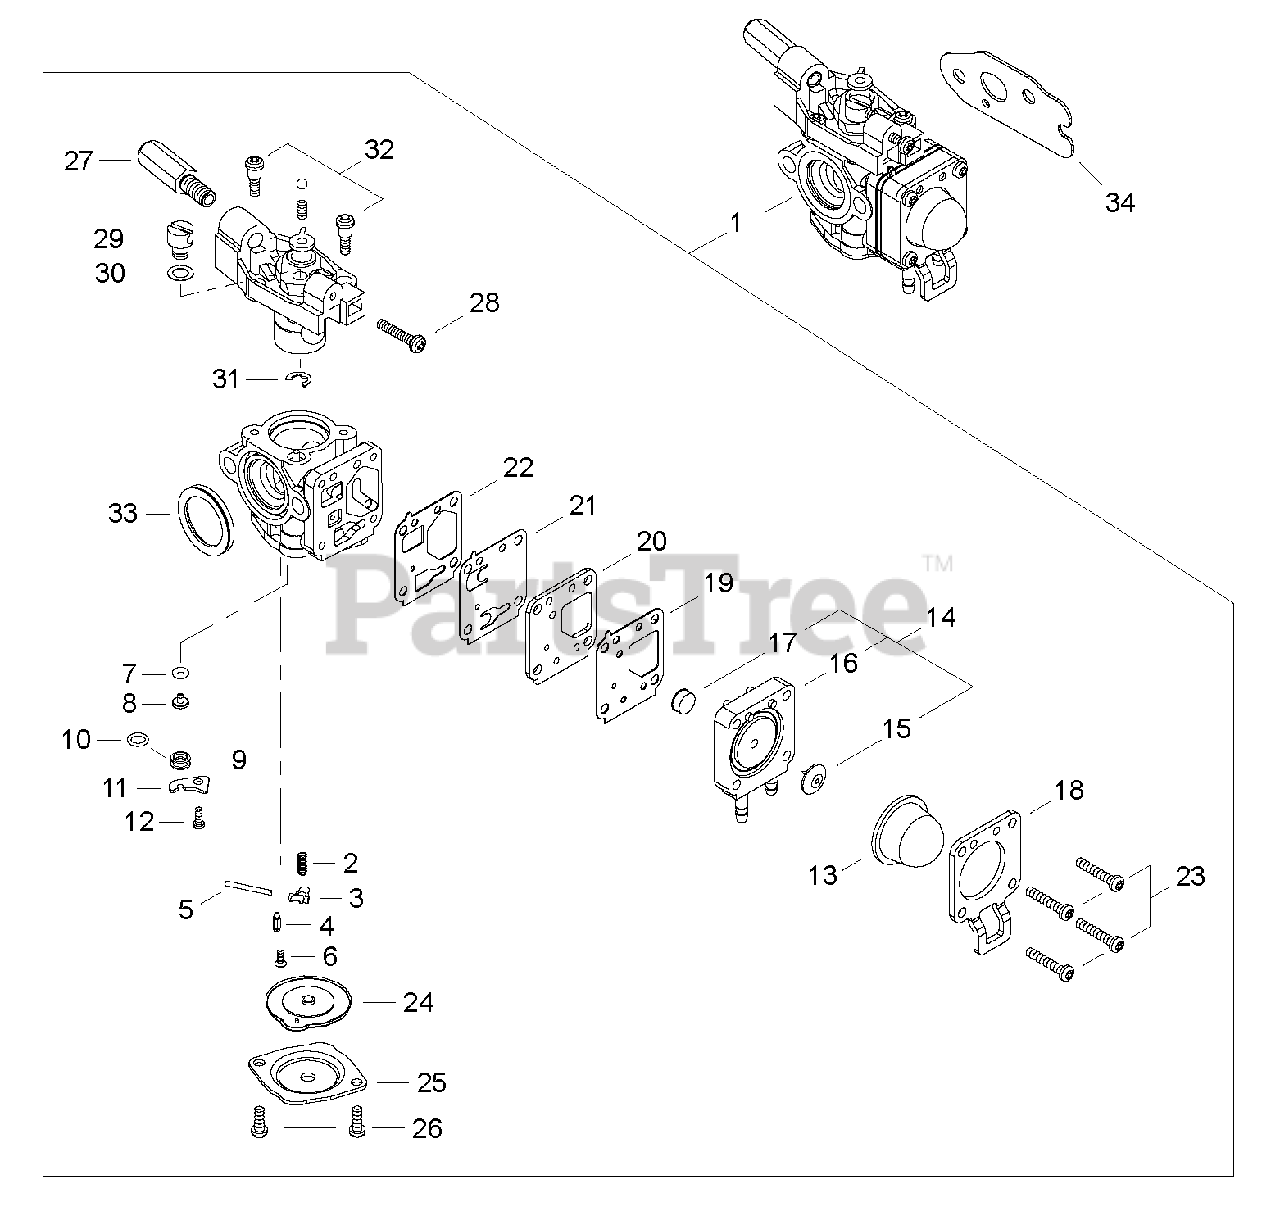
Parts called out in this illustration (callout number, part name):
1	CARBURETOR
2	SPRING, METERING LEVER
3	LEVER, METERING
4	VALVE, INLET NEEDLE
5	PIN, METERING LEVER
6	SCREW, METERING LEVER PIN
8	JET, MAIN
9	VALVE, CHECK
13	BULB, PURGE
14	PURGE BASE ASSY
15	VALVE
16	COVER, PUMP
17	STRAINER
18	RETAINER, PURGE BULB
19	GASKET, PLATE
20	PLATE, PUMP
21	DIAPHRAGM, PUMP
22	GASKET, PUMP
23	SCREW
24	DIAPHRAGM, METERING
25	COVER, METERING
27	NUT, CABLE ADJUST
28	SCREW, IDLE ADJUST
31	RING, RETAINING
33	SEAL
34	GASKET, INTAKE
